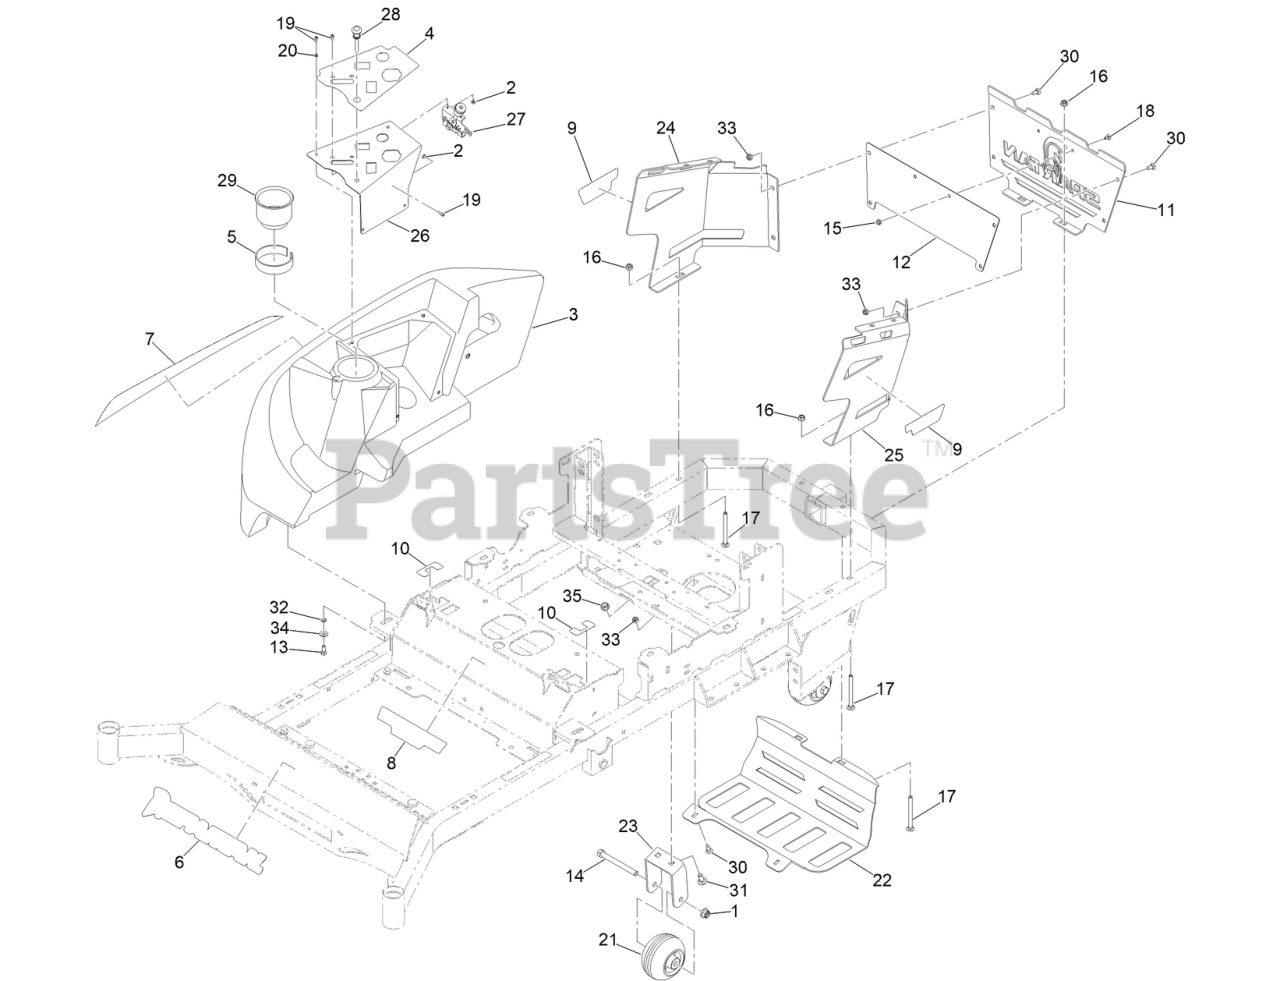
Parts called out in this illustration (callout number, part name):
1	NUT-LOCK
2	NUT-LOCK
3	CONSOLE W/ CUPHOLDER
4	DECAL-CONTROL PANEL
5	TAPE-FOAM
6	DECAL-SPARTAN, FRONT
7	DECAL-TANK
8	DECAL-SRT-XDE GT TRAC MODEL
9	DECAL-COWLING
10	DECAL-MOTION CONTROL
11	PLATE - ENGINE COWLING
12	PLATE -BACKER PLATE
13	SCREW-HH
14	SCREW-HH
15	1/4-20 HEX FLANGE NUT W/SERR ZINC
17	3/8-16 X 4 CARRIAGE BOLT ZINC
18	1/4-20 X 1/2 CARRIAGE BOLT,YZ
19	10-24 X 1/2 SOCKET C/S 18-8 SS
20	#10 SPLIT LOCKWASHER 18-8 SS
21	MWR ANTI-SCALP WHL W/O GREASE FITTING
22	MUFFLER GUARD [GRAY]
23	MWR STABILIZER MTG BRKT PAINT
24	2021 RT/SRT ENGN COWLING RTPAINTED
25	2021 RT/SRT ENGN COWLING LT PAINTED
26	RT 45 KEY MNT
27	MWR THROTTLE CABLE ASSY W / HANDLE
28	MWR CHOKE CABLE ASSM
29	CUP HOLDER
30	BOLT-CARR
31	SCREW-CARR
32	WASHER-LOCK
34	WASHER-FLAT
35	NUT-HF
